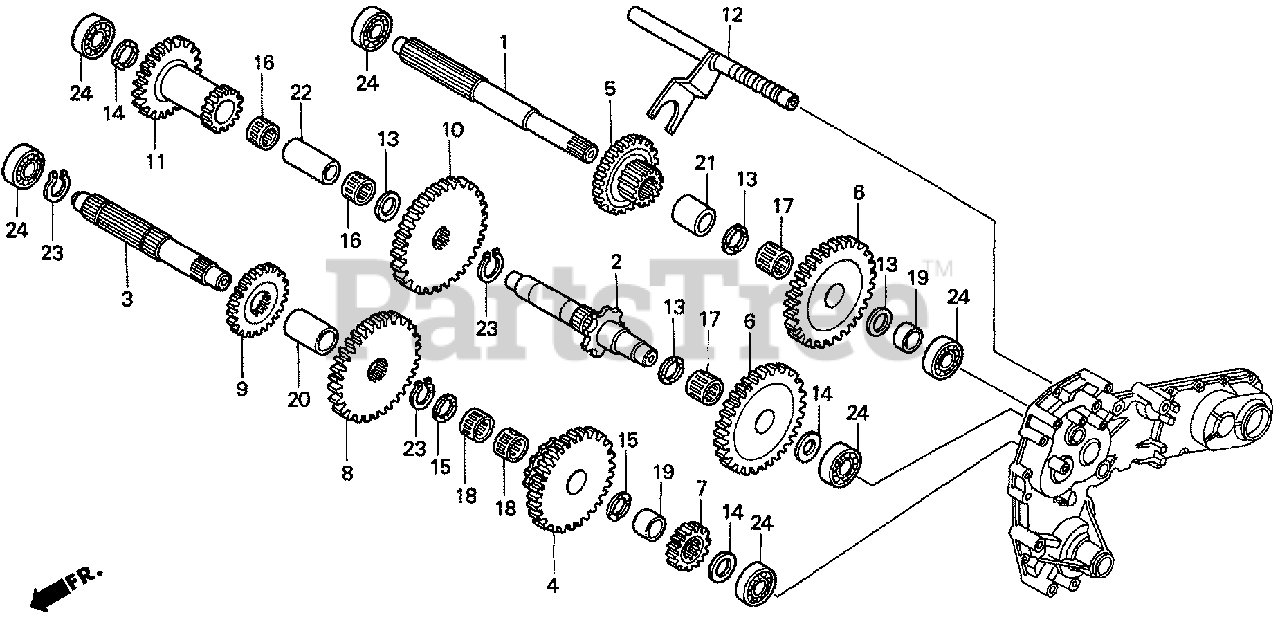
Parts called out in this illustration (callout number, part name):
1	SHAFT, INPUT
2	COUNTERSHAFT
3	SHAFT, FINAL
4	GEAR, FINAL
5	GEAR, CHANGE
6	GEAR, IDLE DRIVE
7	GEAR, REDUCTION DRIVE
8	GEAR, LOW DRIVE
9	GEAR, HIGH DRIVE
10	GEAR, REDUCTION ROTARY DRIVEN
11	GEAR, REVERSE IDLE
12	SHAFT, SHIFT FORK
13	WASHER, THRUST (17MM)
14	WASHER, THRUST (15MM)
15	WASHER, THRUST (17MM)
16	BEARING, NEEDLE (17X21X15)
17	BEARING, NEEDLE (17X22X20)
18	BEARING, NEEDLE (18X22X17)
19	COLLAR, DISTANCE
20	COLLAR, FINAL SHAFT
21	COLLAR, INPUT SHAFT
22	COLLAR, REVERSE IDLE GEAR
23	CIRCLIP, OUTER (20MM)
24	BEARING, RADIAL BALL (6202)
